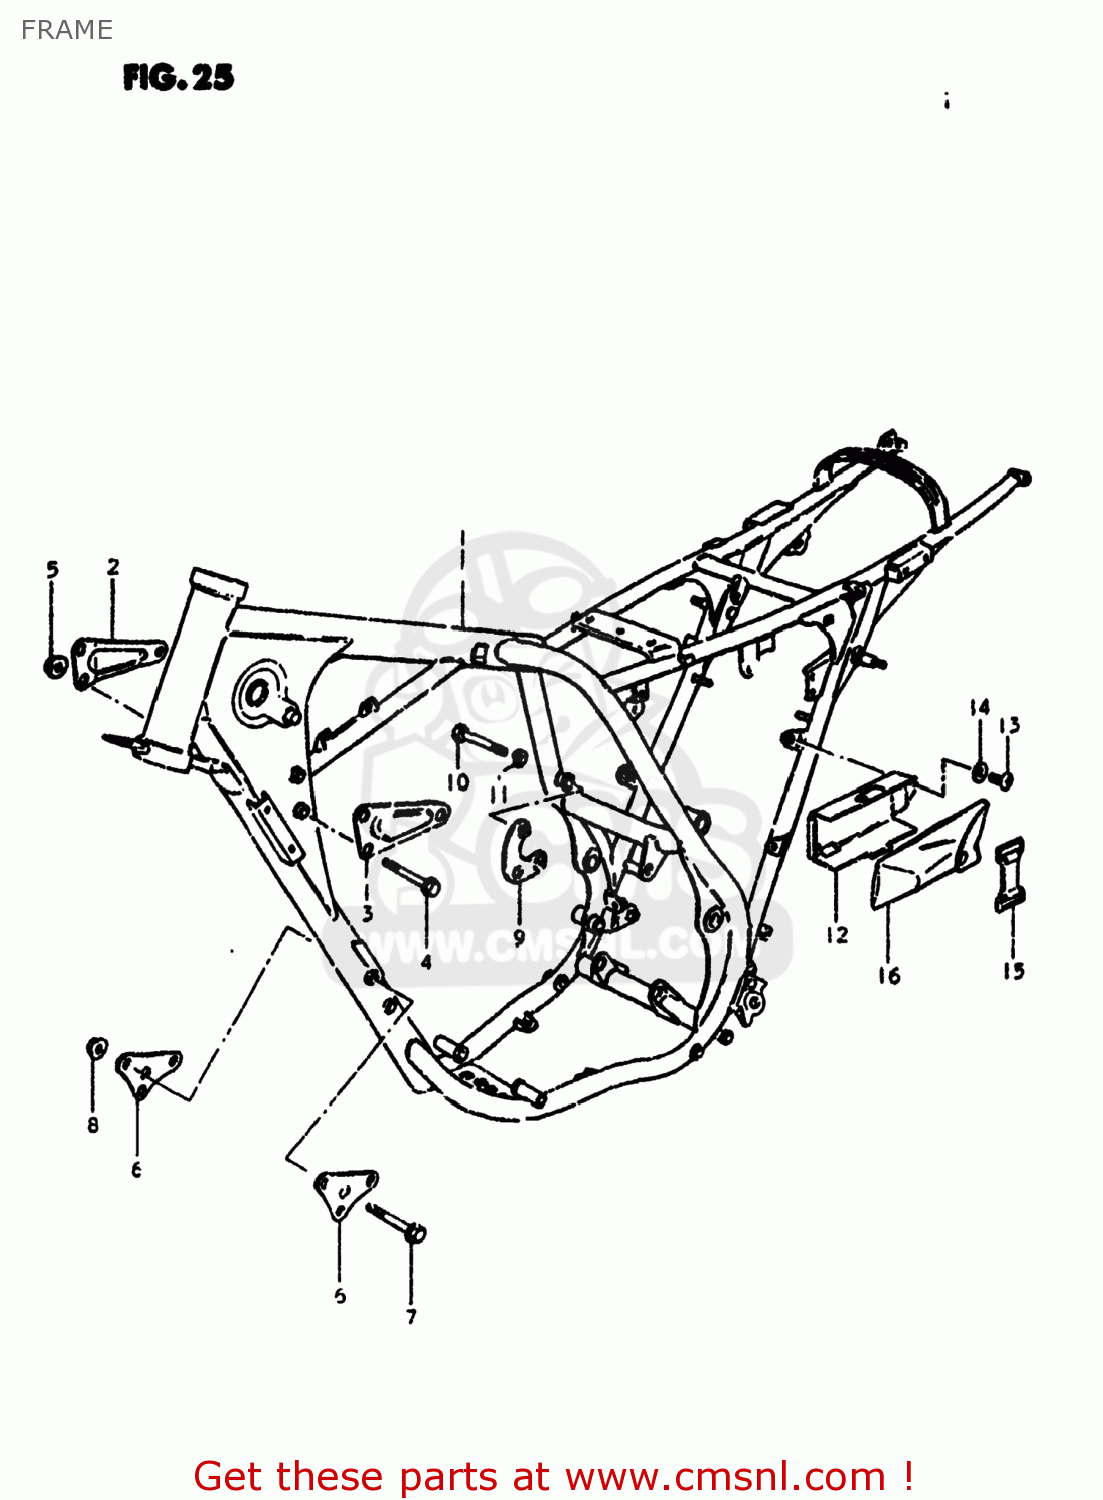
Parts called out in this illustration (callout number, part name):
1	FRAME
2	PLATE COMP,ENGINE MOUNTING
3	PLATE,ENGINE MOUNTING
4	BOLT (6X70)
5	NUT
6	PLATE,ENGINE MOUNTING
7	BOLT (8X70)
8	NUT
9	PLATE,ENGINE MOUNTING
10	BOLT
11	LOCK WASHER
12	HOLDER,TOOL
13	SCREW
14	WASHER 6MM
15	BAND
16	TOOL SET
